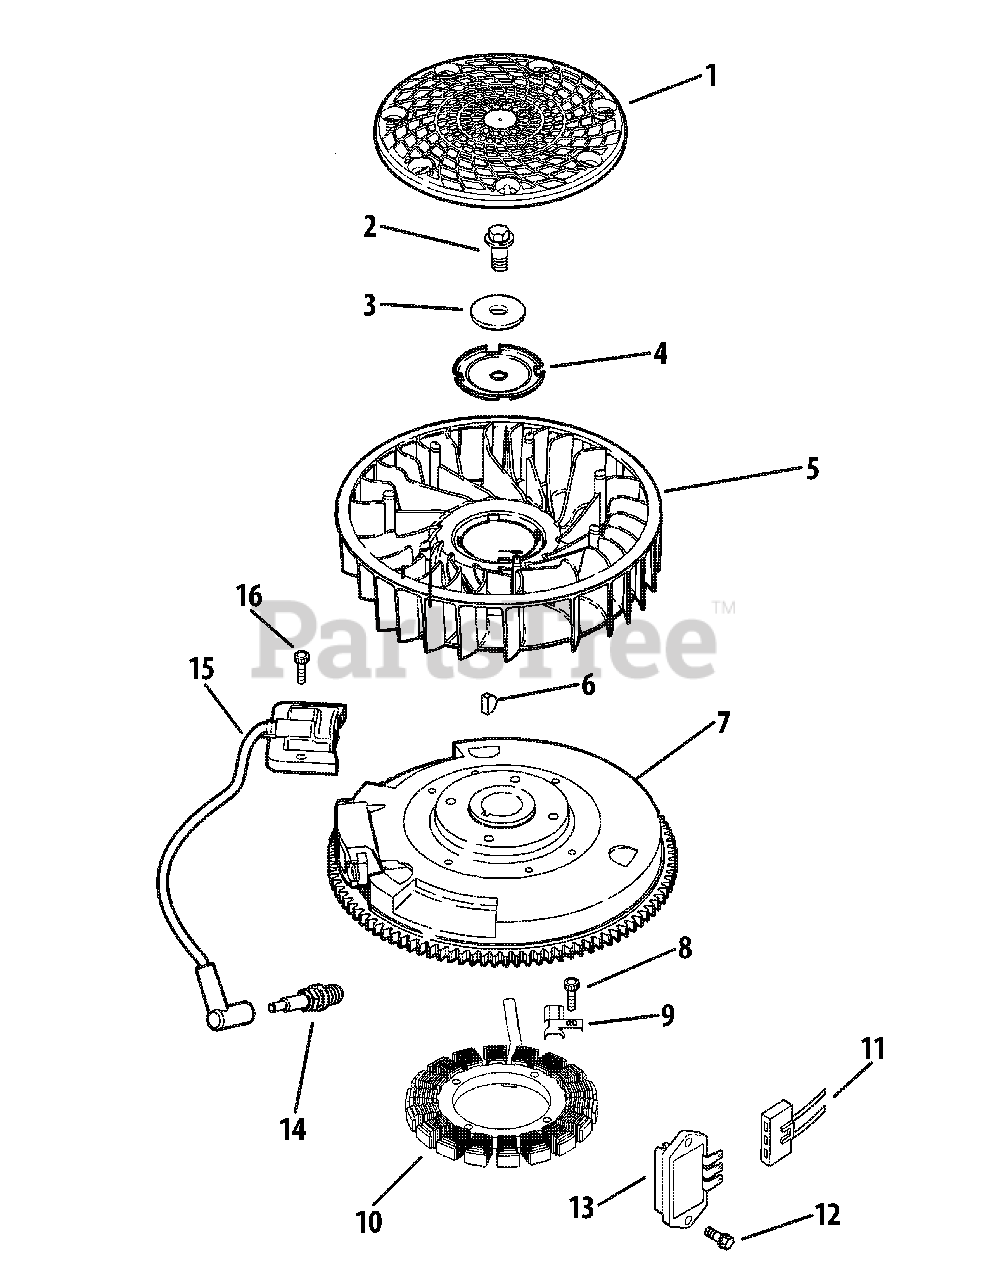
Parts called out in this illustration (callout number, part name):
2	Flg Screw, M10 x 1.5 x 45
3	Flat Washer, 13/32''
4	Fan Mounting Plate
6	Key, 3/16" x 5/8 "
7	Flywheel
8	Skt Thd Frm Screw, M5 x 0.8 x 25
9	Sator Wire Clip
10	15 Amp Stator Kit
11	Connector (3 Contact)
12	Flg Thd Frm Screw, M5 x 0.8 x 20
13	Rectifer-Regulator
14	Spark Plug
15	Ignition Module
16	Skt Thd Frm Screw, M5 x 0.8 x 25
